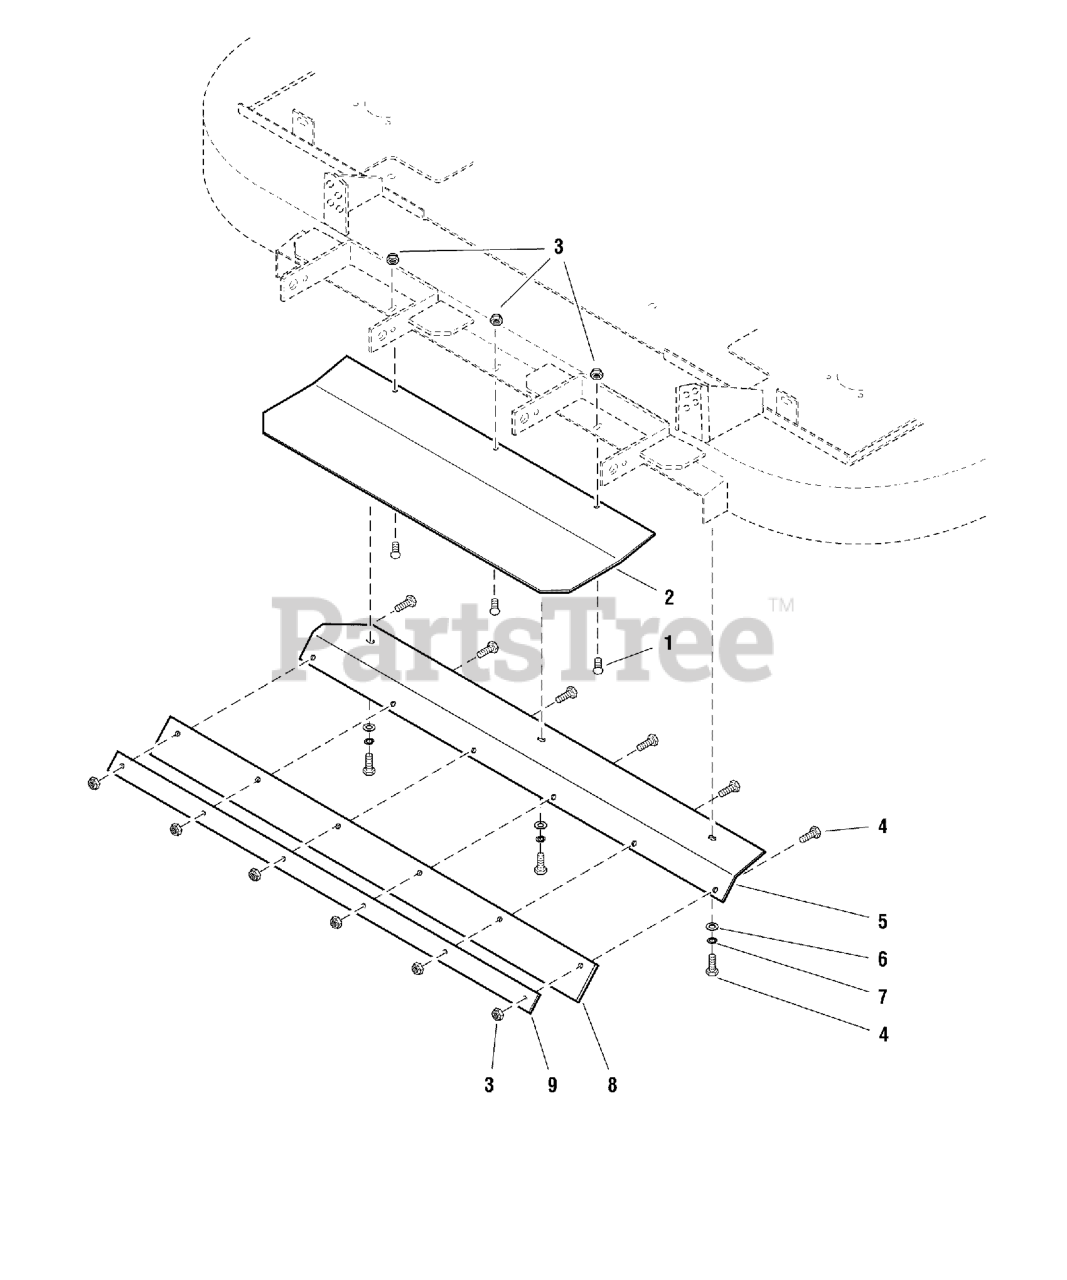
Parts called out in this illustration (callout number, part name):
1	BOLT, 5/16-18 X 3/4", CARRIAGE
2	PLATE, SHIELD - RED
3	NUT, 5/16-18 HEX NYLON LOCK
4	BOLT, 5/16-18 X 1" GD5 YZ
5	PLATE, ANGLE DEFLECTOR
6	WASHER, 5/16" SAE
7	WASHER, 5/16 LOCK CZ
8	DEFLECTOR
9	PLATE, RETAINING
